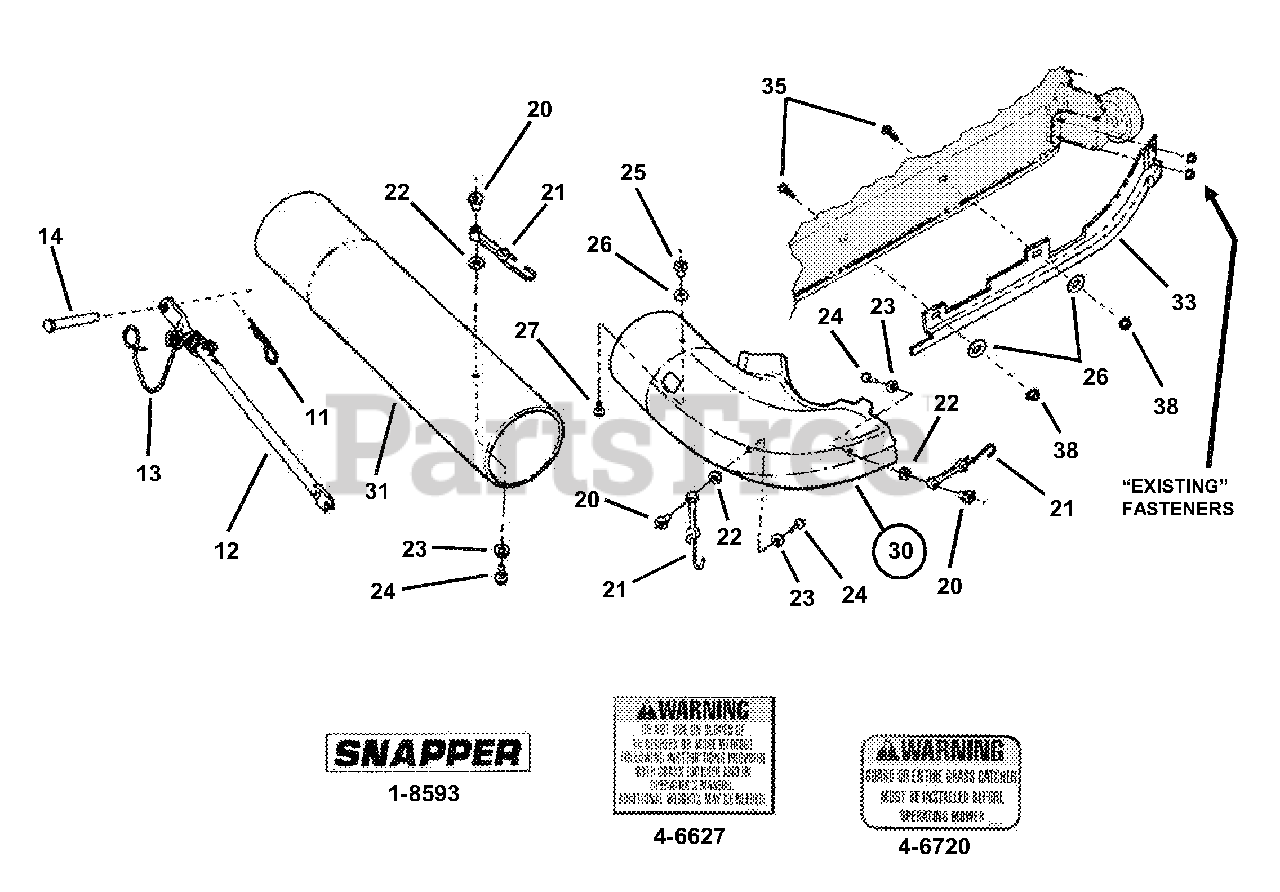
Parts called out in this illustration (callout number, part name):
1-8593	DECAL, SNAPPER
4-6627	DECAL, GRASS BAG WARNING
4-6720	DECAL, CHUTE DEFLECTOR
11	PIN, 3/32 x 1-1/2" Hair
12	BRACE, Rear
13	ASS'Y, Spring & Hook
14	PIN, 5/16 x 1-11/16" Clevis
20	NUT, #10-24 x 5/8" Weld
21	STRAP, Adapter/Tube
22	WASHER, 3/16" Flat
23	WASHER, 7/32" Flat
24	SCREW, #10-24 x 5/8" Pan Hd.
25	TEENUT, 5/16-18
26	WASHER, 11/32" Flat
27	SCREW, 5/16-18 x 5/8" Nyloc
30	ADAPTER
31	TUBE, Grass (32" long)
33	BAFFLE, 38" Deck
35	SCREW, 5/16-18 x 3/4" Hex
38	NUT, 5/16-18 Hex Center Lock
